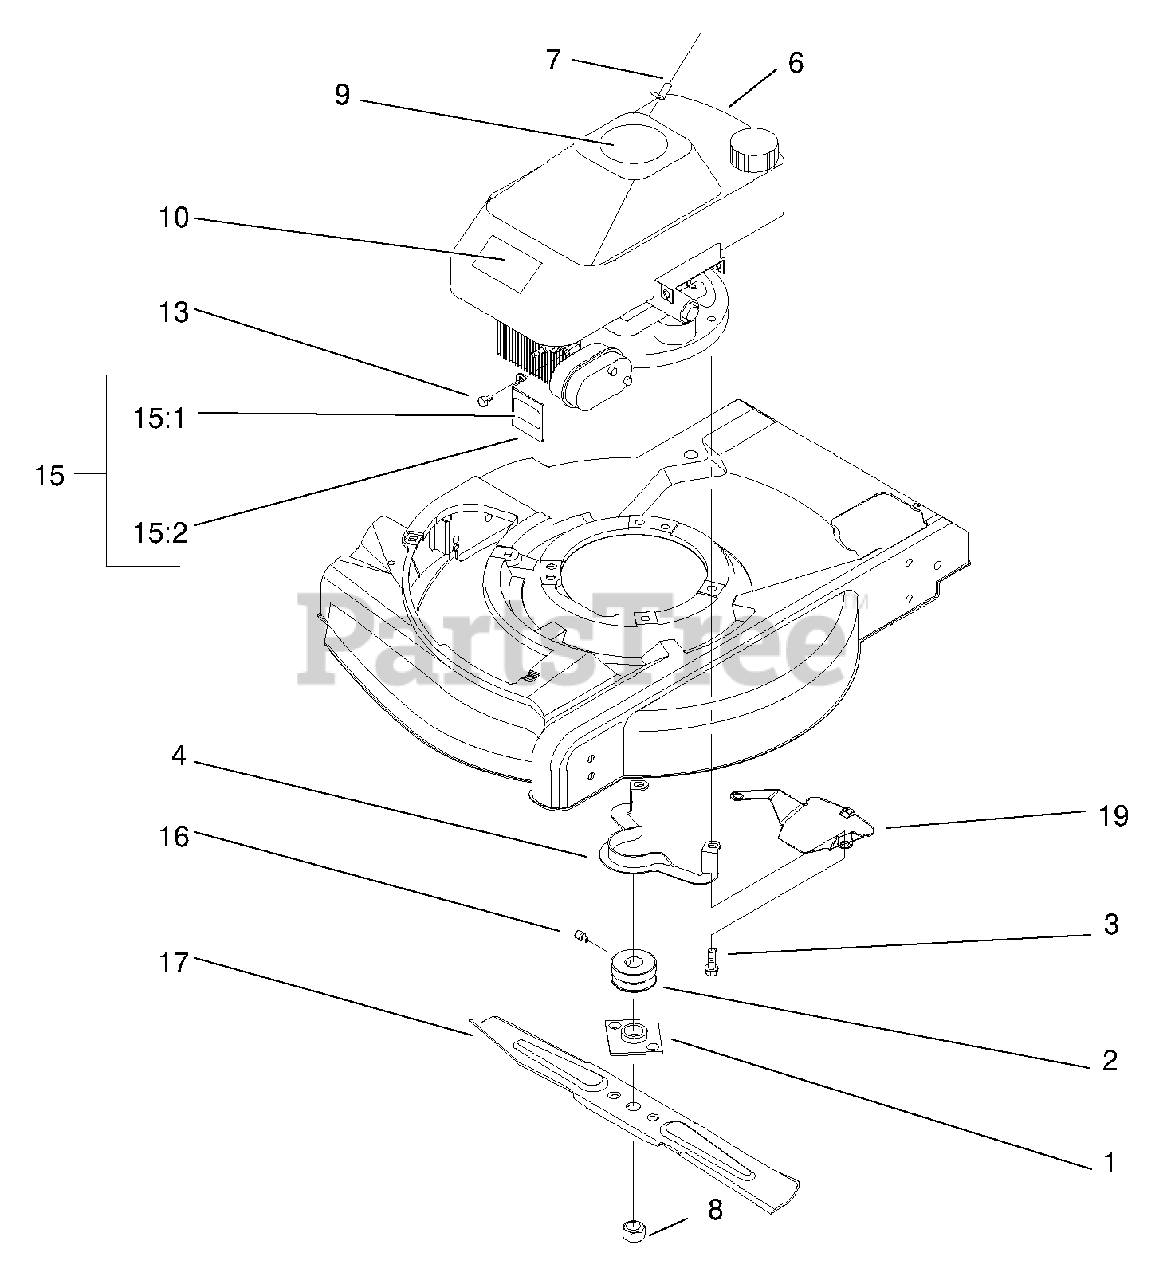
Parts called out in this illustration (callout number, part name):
1	Plate & Collar ASM
3	Screw-Taptite w/Patch
4	Guide-Belt
7	Rope-Stop
8	Nut-Blade
9	Decal-Recoil
10	Applique
15	ASM-Muffler Guard
15:1	Decal-Surface, Hot
15:2	Guard-Muffler
16	Screw-Set,Cone Point
17	Blade
19	Shield-Grass
